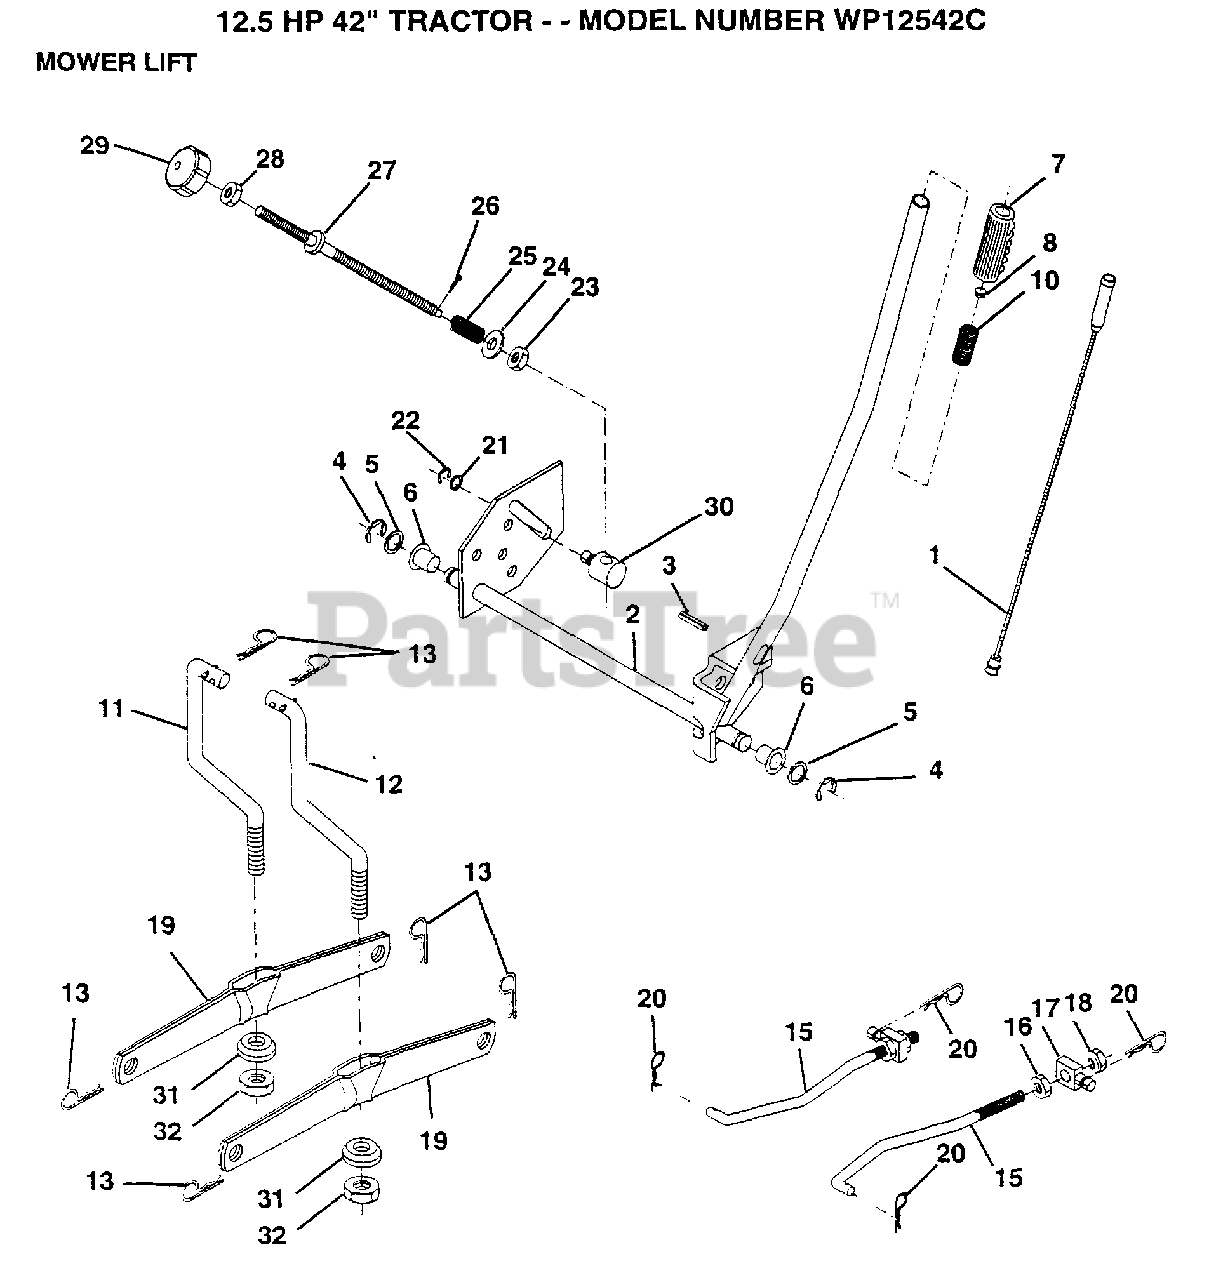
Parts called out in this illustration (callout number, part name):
1	WIRE.ASM.INNER
2	SHAFT.ASM.LIFT.RH
3	PIN GROOVE
5	WASHER
6	NYLON BEARING
7	GRIP
15	LINK.FRONT
16	NUT
17	TRUNION
18	NUT.LK.W/WSH.1/2.
19	ARM SUSP REAR
20	RETAINER.SPRING
21	WASHER
22	KLIP RING
23	NUT T
24	WASHER
25	SPRING T
27	ROD LIFT LT
28	NUT
29	KNOB INF 3/8-16
30	TRUNION LT
31	BEARING PVT LH
32	NUT.LOCK.3/8-24
